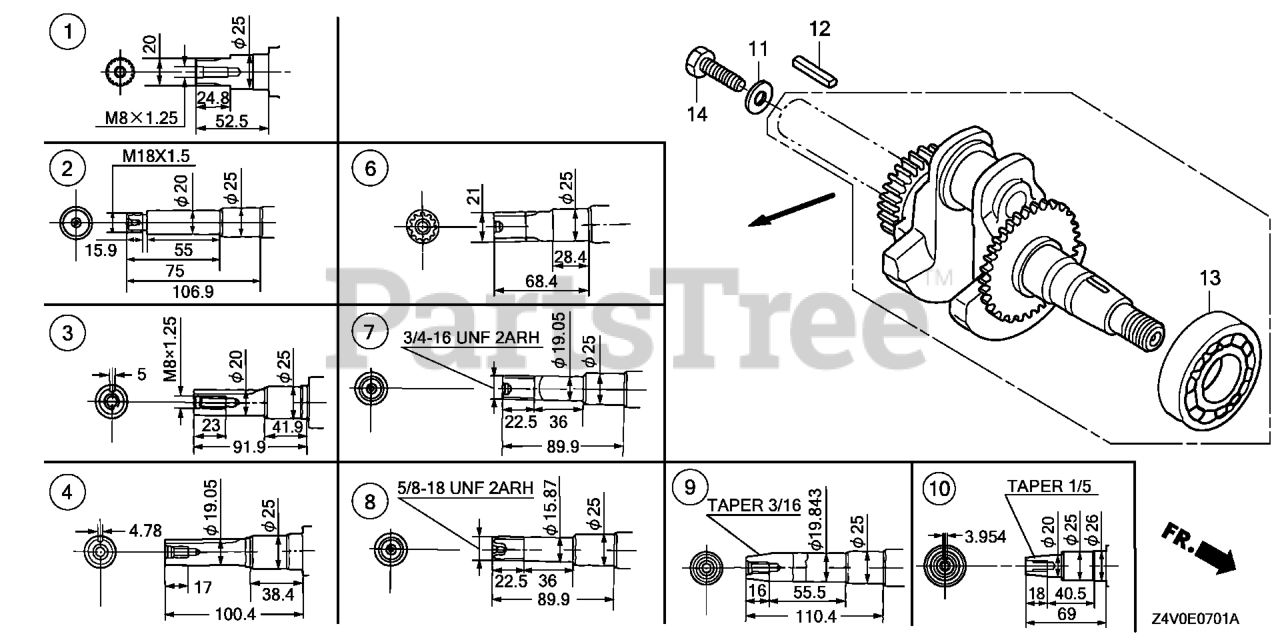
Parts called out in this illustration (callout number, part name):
4	CRANKSHAFT
12	KEY (4.78X4.78X38)
13	BEARING, RADIAL BALL (6205)
13	BEARING, RADIAL BALL (6205) (NSK)
